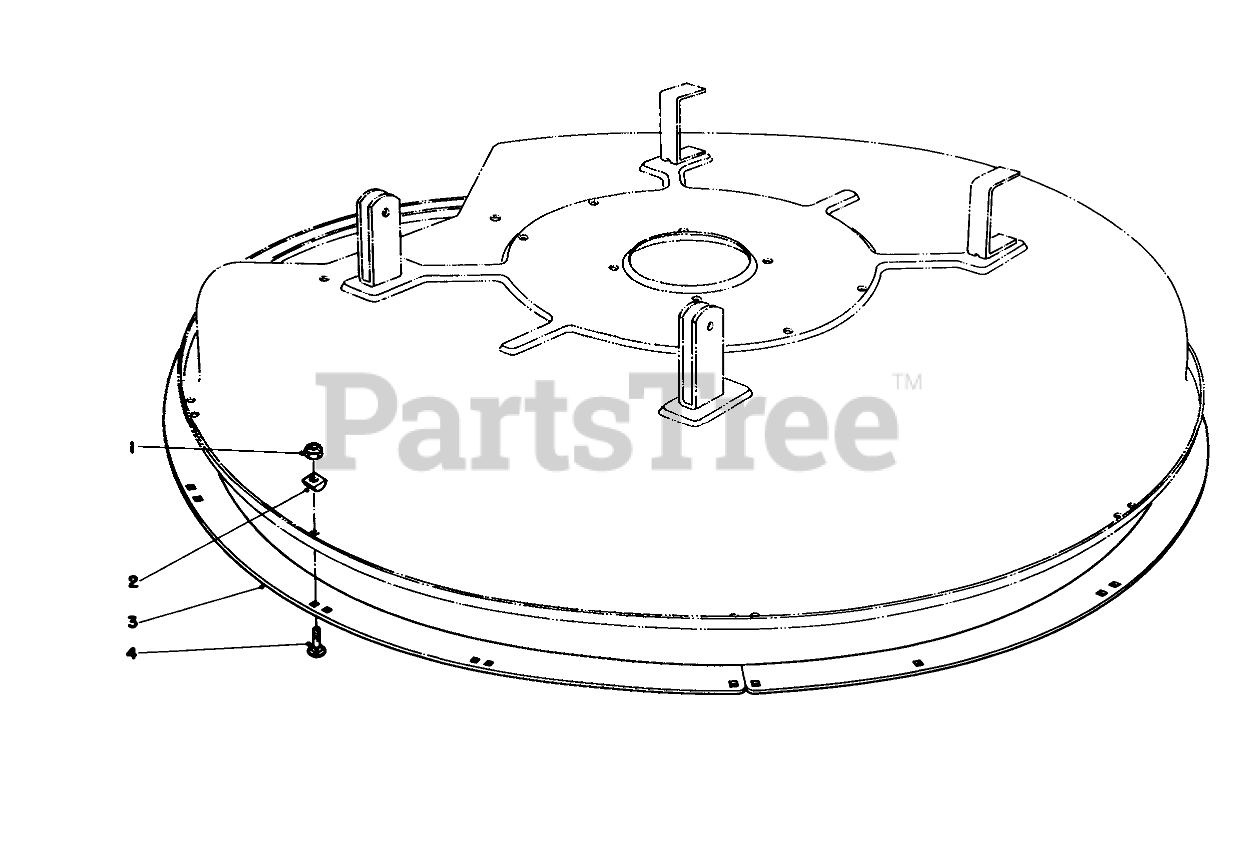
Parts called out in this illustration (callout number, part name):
1	NUT-LOCK, NI
2	Spacer-Deck Ring
3	DECK RING B
4	BOLT-CARR
